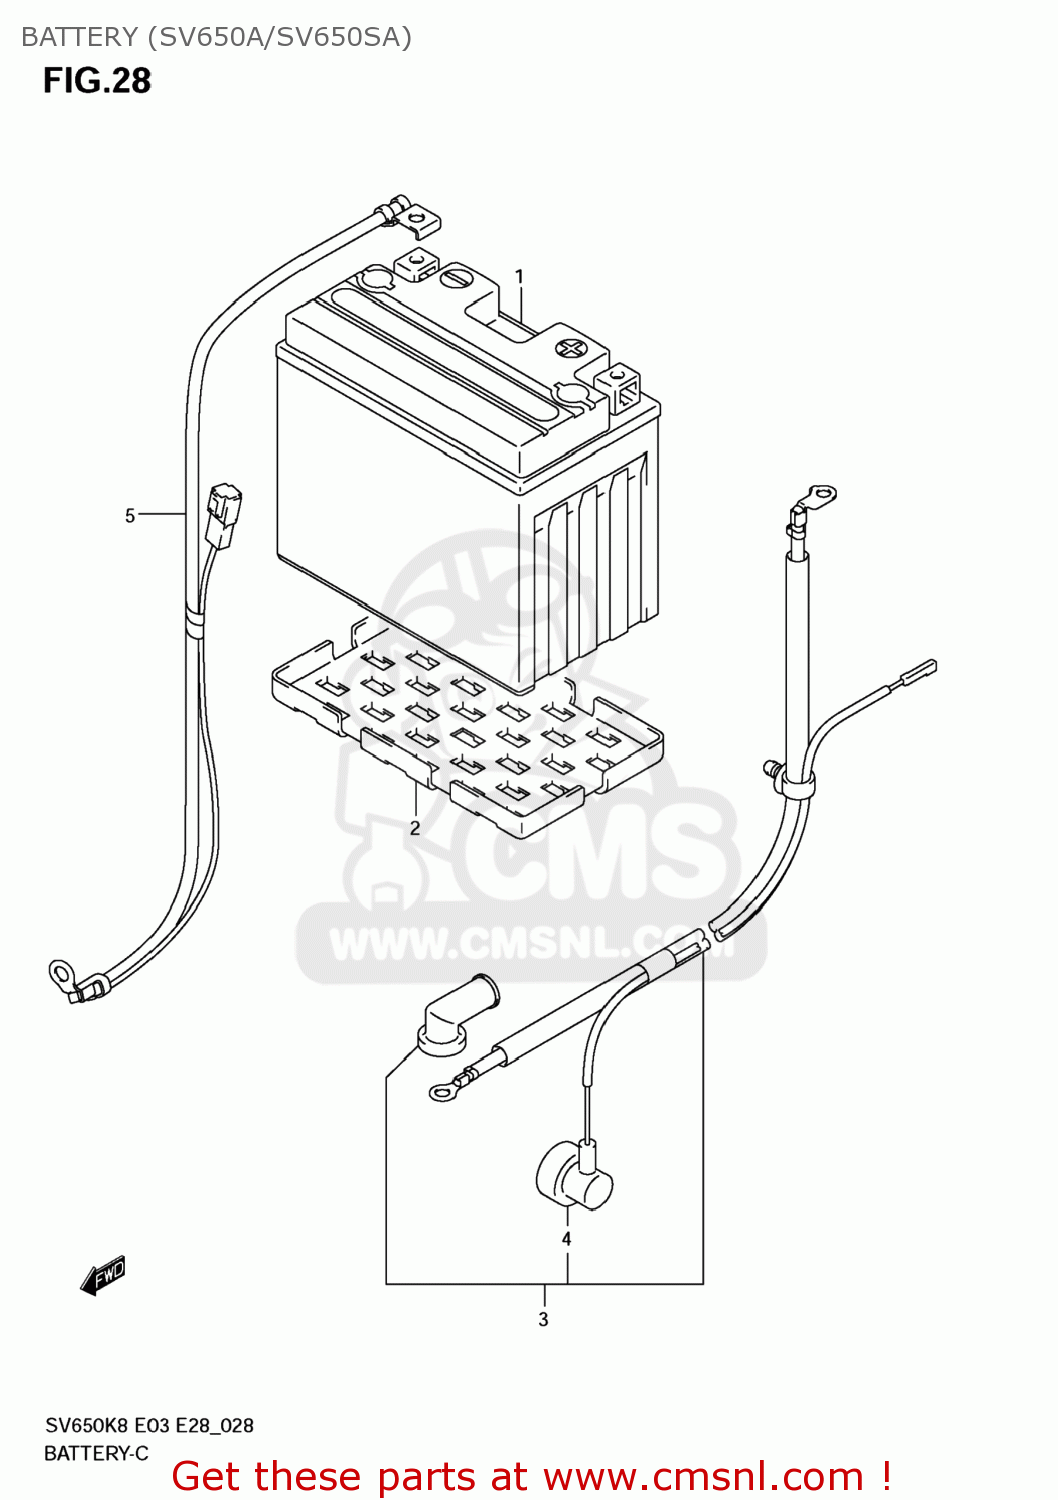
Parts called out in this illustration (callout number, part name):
1	BATTERY(YT12A-BS,12V10.5AH)
2	PROTECTOR,BATTERY
3	WIRE,STARTER MOTOR LEAD
4	CAP,OIL PRESSURE SWITCH
5	WIRE,BATTERY MINUS LEAD
